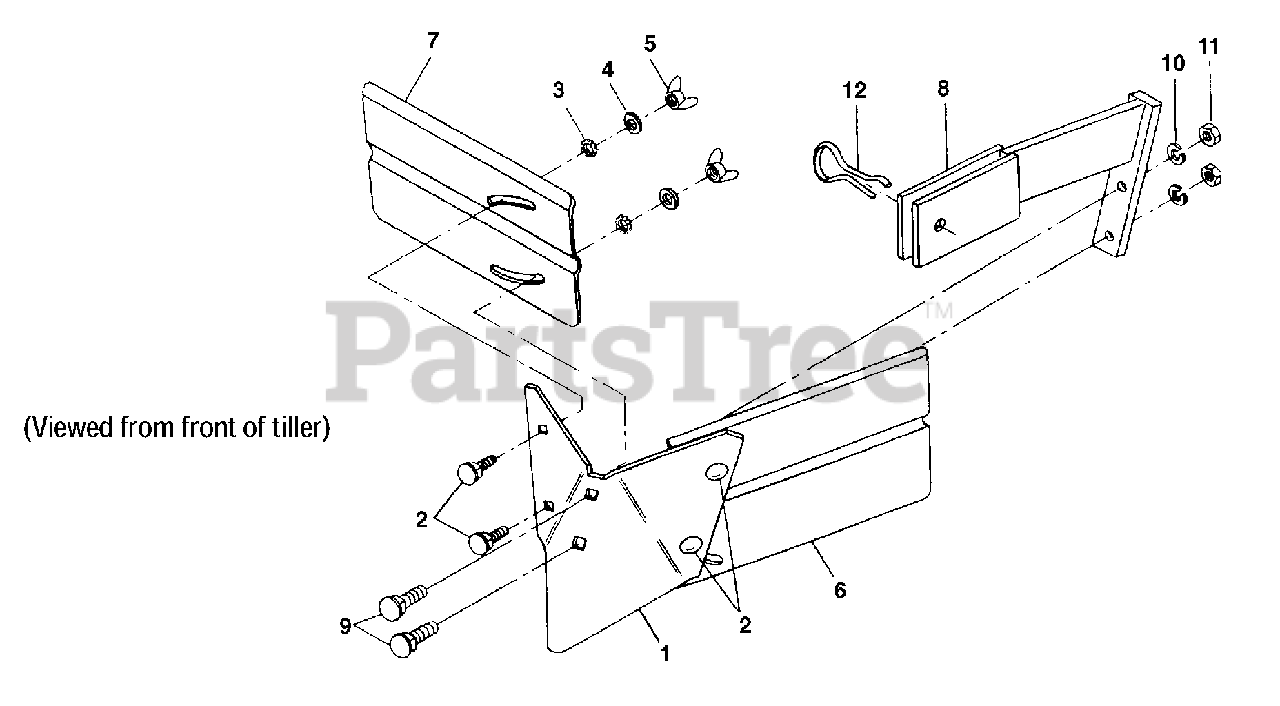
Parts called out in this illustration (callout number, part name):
1	Furrower-blade only
2	Carriage Screw-5/16-18 x 3/4
3	Star Washer-external tooth, 5/16
4	Plain Washer-5/16 S.A.E
5	Wing Nut-5/16-18
6	Hiller Wing-left
7	Hiller Wing-right
8	Bracket-blade mounting
9	Carriage Screw-blade mounting, 3/8-16 x 1-1/2
10	Lockwasher-3/8, plated
11	Nut-hex, 3/8-16, plated
12	Pin-clinch
